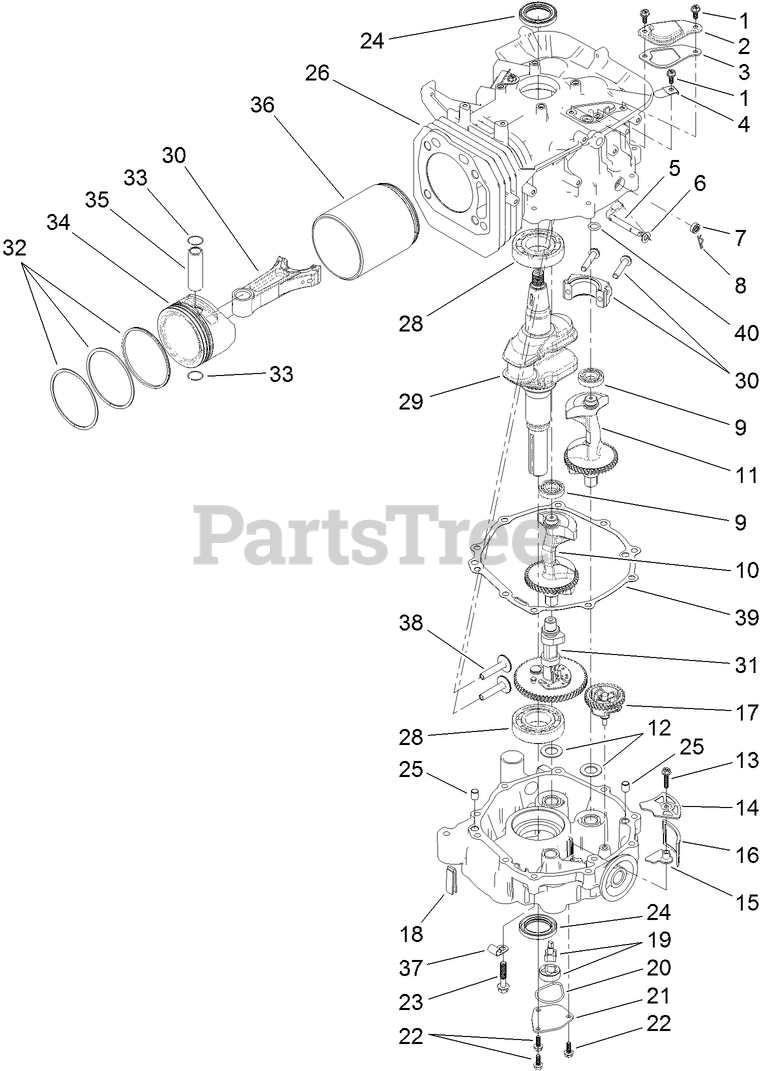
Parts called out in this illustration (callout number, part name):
1	SCREW-HHF
2	PLATE-BREATHER
3	GASKET-BREATHER
4	VALVE-REED
5	SHAFT-GOVERNOR
6	WASHER-PLAIN
7	SEAL-OIL
8	PIN-HAIR
9	BEARING-BALL
10	BALANCER-RH
12	WASHER
13	SCREW-HHF
14	COVER-STRAINER, OIL
15	PLATE-BAFFLE, OIL
17	GOVERNOR ASM
18	DEFLECTOR-OIL, RUBBER
19	PUMP-OIL
21	COVER-PUMP, OIL
22	SCREW-HHF
23	SCREW-HHF
24	SEAL-OIL
25	PIN-DOWEL
28	BEARING-BALL
29	CRANKSHAFT
30	CONNECTING ROD ASM
31	CAMSHAFT
32	RING SET
33	RING-RETAINING, PISTON PIN
34	PISTON
35	PIN-PISTON
36	CRANKCASE
37	CLAMP-J
38	LIFTER-VALVE
39	GASKET-CRANKCASE
40	O-RING
